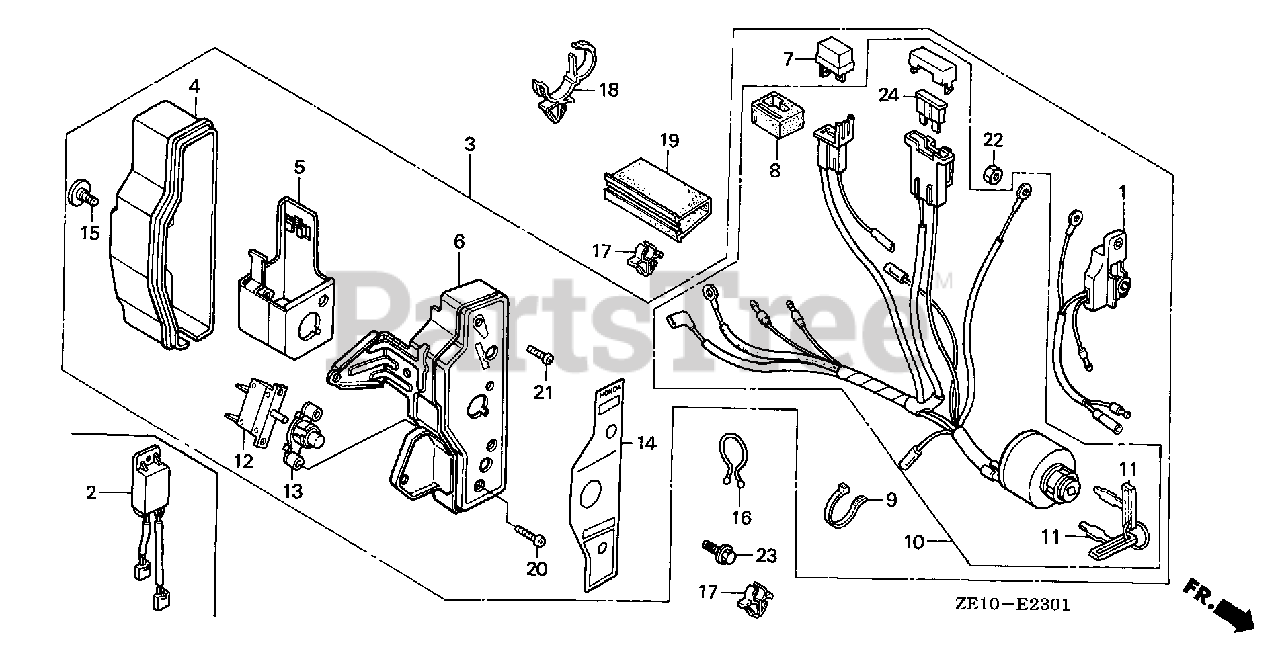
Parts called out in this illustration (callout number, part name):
1	ALERT UNIT, OIL
3	BOX ASSY., CONTROL *R8* (EXP-ALERT) (BRIGHT RED)
4	CASE, CONTROL
5	BRACKET, CASE MOUNTING
6	PANEL, CONTROL *R280* (POWER RED)
7	RECTIFIER ASSY., SILICON (STANLEY)
8	SUSPENSION, CONNECTOR
10	SWITCH ASSY., COMBINATION
10	SWITCH ASSY., COMBINATION Use from Engine SN 2983151.
11	KEY
12	PROTECTOR, CIRCUIT (1.0A)
13	LENS ASSY., PROTECTOR
14	PANEL, CONTROL BOX (EXTERNAL-ALERT)
15	SCREW, SPECIAL (6X12)
16	CLIP, PURSE LOCK
17	CLIP, CORD
18	STRAP, WIRE HARNESS (25MM) (BLACK)
19	TUBE, FASTENER (30MM)
20	SCREW, PAN (3X12)
21	SCREW, PAN (4X12)
22	NUT, HEX. (4MM)
23	BOLT, FLANGE (6X10)
24	FUSE, BLADE (5A)
